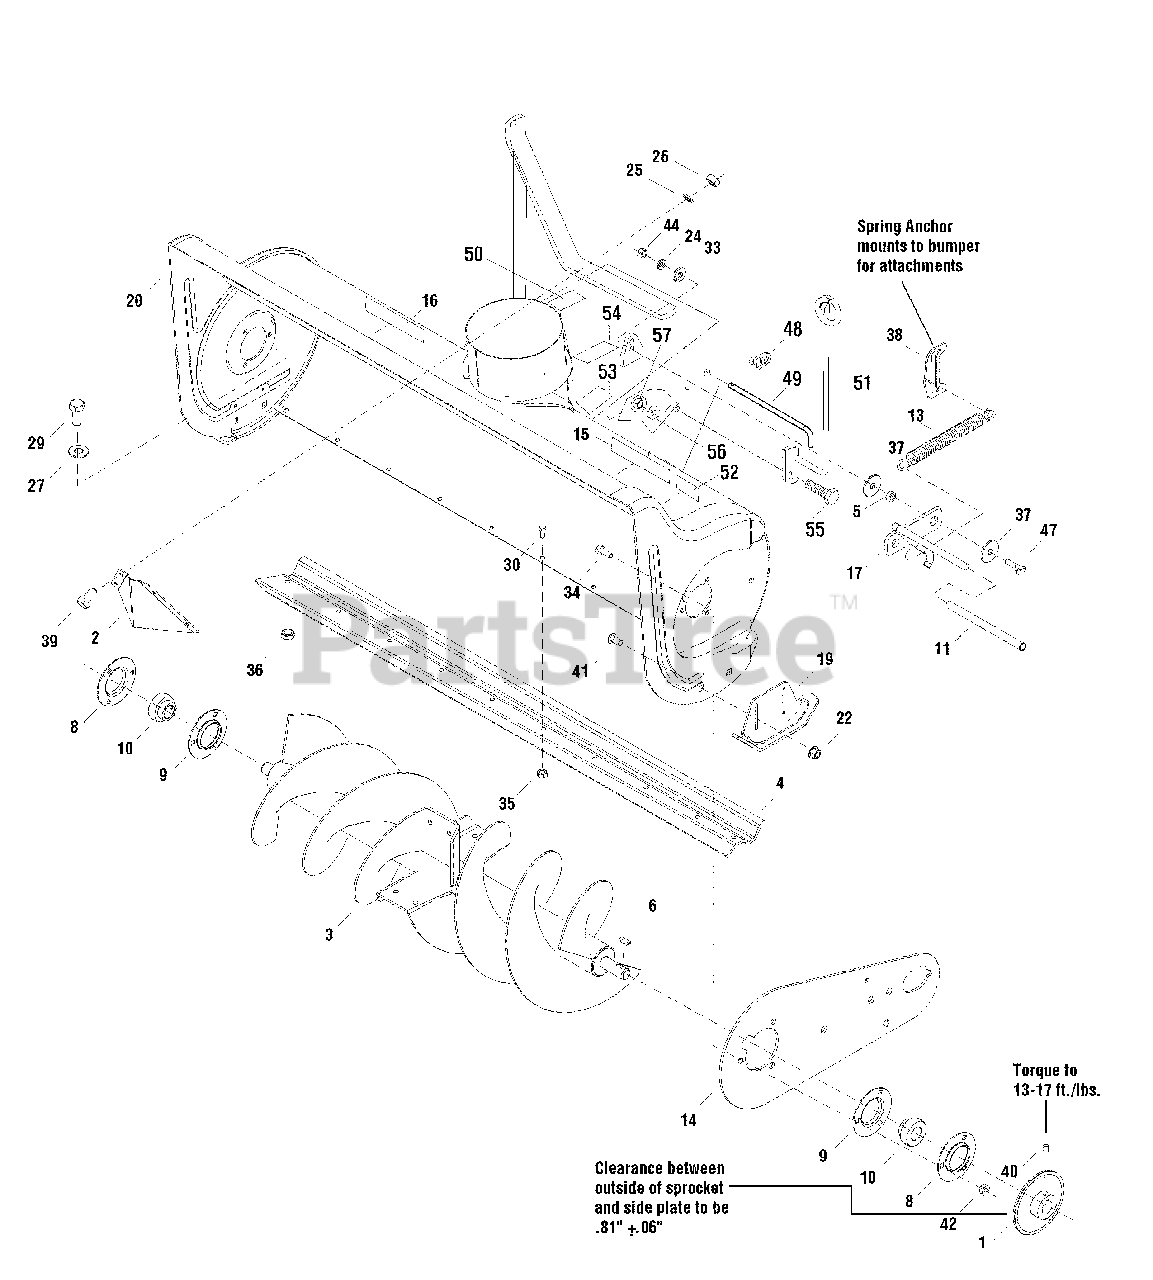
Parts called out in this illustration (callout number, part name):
1	SPROCKET, 24 Teeth
3	ROTOR ASSEMBLY
4	BLADE, Scraper, 42"
8	FLANGE, Bearing
9	FLANGE, Bearing
10	BEARING, Ball
13	SPRING, Extension
14	PLATE, Side
15	DECAL, Caution
16	DECAL, Caution, Rear Wheel Weights Required
17	LEVER, Spring Assist-Assembly
19	SKID & WEAR ASSEMBLY
20	BODY & FRAME ASSEMBLY
22	NUT, ESNA, Flange 3/8-16
24	LOCKWASHER, 3/8
25	LOCKWASHER
26	NUT, Hex, 5/16-18
29	CAPSCREW, Hex Head, 5/16-18 x 3/4
30	CAPSCREW, Hex Head, 1/4-20 x 5/8
33	LOCKWASHER .38
34	CAPSCREW, Hex Head, 5/16-18 x 7/8
35	NUT, Hex Centerlock, 1/4-20
36	LOCKNUT, Hex, 5/16-18
37	WASHER, 3/8
38	ANCHOR, Spring
39	CAPSCREW, Hex Head, 5/16-18 x 5/8
40	SCREW, Set, Square Head, Cup Point 5/16-18 x 1/2, G8
41	BOLT, Carriage 3/8-16 x 3/4 Standard Neck
42	NUT, Hex Flange Lock, 5/16-18
44	NUT-Hex 3/8-16
47	CAPSCREW
48	PIN, Safety
49	PIN, Clevis
50	DECAL, Caution, Spring Tension
51	GUIDE, Cable
52	DECAL, Danger Auger
53	DECAL, Model Number & Serial Number, Not Serviced
54	DECAL, OPEI, Not Serviced
55	CAPSCREW, Hex Head, 5/16-18 x 1
56	WASHER, 5/16
57	NUT, Hex, 5/16-18
